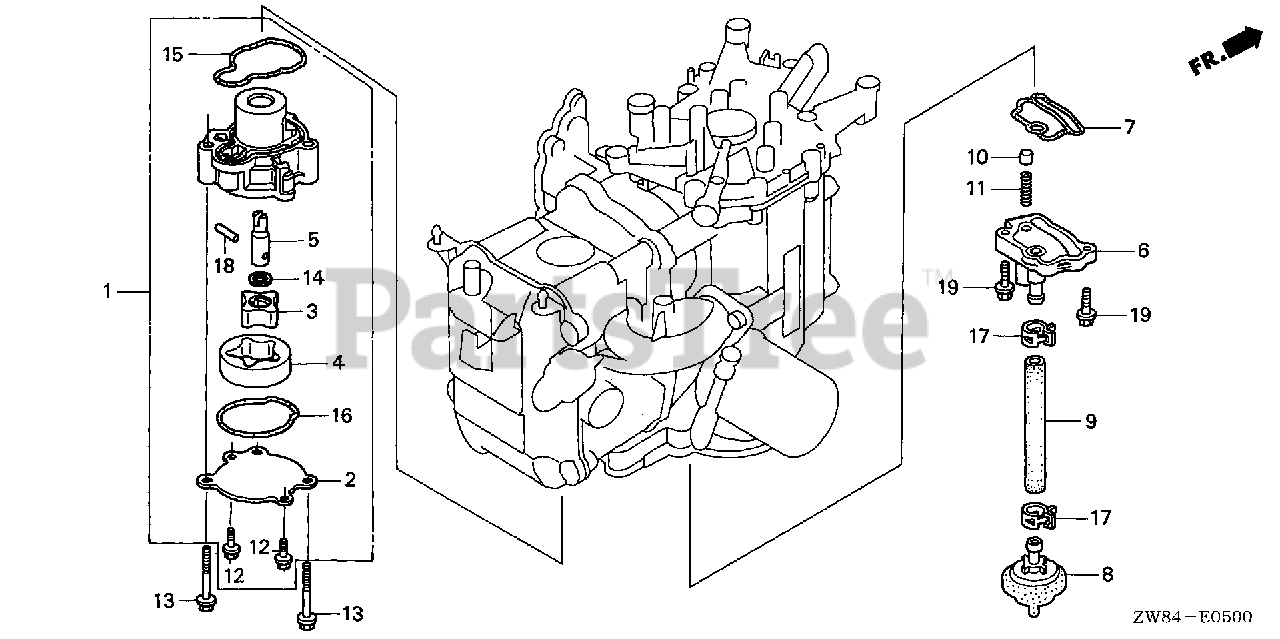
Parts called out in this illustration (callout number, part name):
1	PUMP ASSY., OIL
2	COVER, OIL PUMP
3	ROTOR, OIL PUMP (INNER)
4	ROTOR, OIL PUMP (OUTER)
5	SHAFT, OIL PUMP
6	FLANGE, OIL STRAINER
7	O-RING, OIL STRAINER FLANGE
8	STRAINER, OIL
10	VALVE, CHECK
11	SPRING, CHECK VALVE
12	BOLT, FLANGE (5X12) (CT200)
13	BOLT, FLANGE (6X35)
14	WASHER, THRUST (11MM)
15	O-RING, OIL PUMP
16	O-RING, PUMP COVER
17	CLAMP, TUBE (D17)
18	ROLLER (4X15.8)
19	BOLT, FLANGE (6X22)
